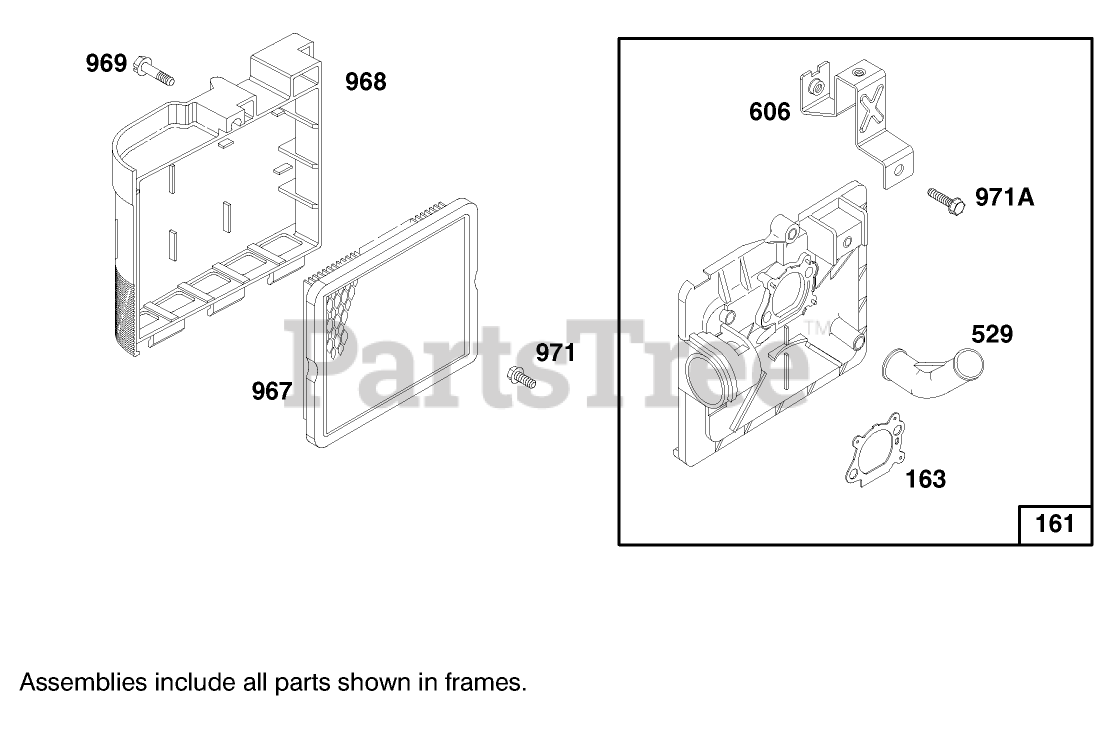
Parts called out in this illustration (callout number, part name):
161	Base-Primer, Air Cleaner
163	Gasket-Cleaner, Air
529	Grommet
606	Strap-Bracket
967	Filter-Air Cleaner, Cartridge
968	Air Cleaner Cover
969	Screw(A/C Cover)
971	Screw-Hex.
971A	Screw-Hex.
